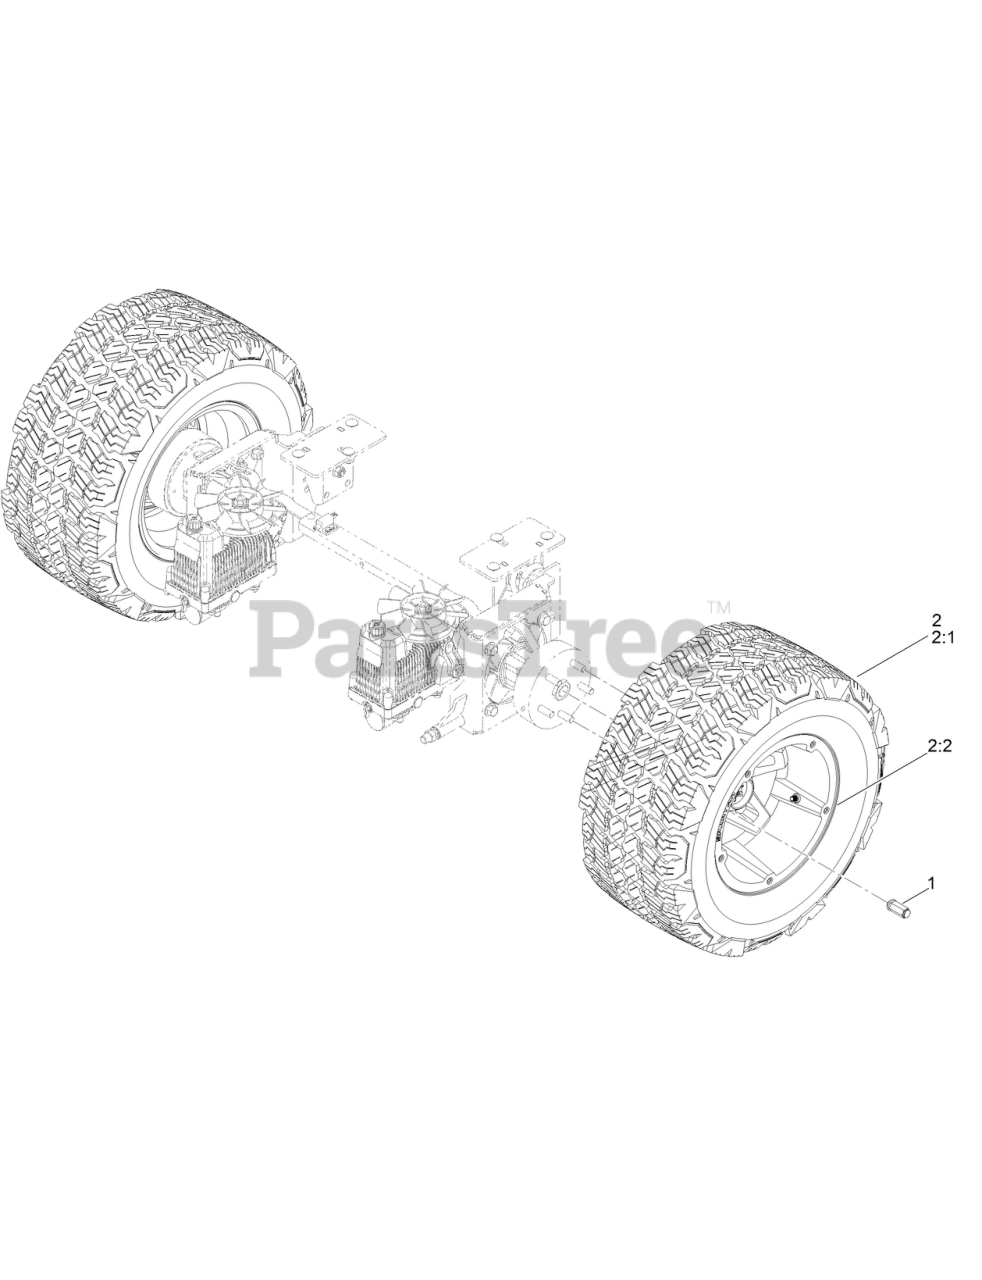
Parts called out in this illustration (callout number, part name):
1	LUG NUTS
2	2019 MWR XD WHEEL AND 24X14-R12 TIRE
2:1	24 X 14 R12 SOFT RIDE RADIAL TIRE ONLY
2:2	12 X 8.5 416 STYLE WHEEL ONLY
